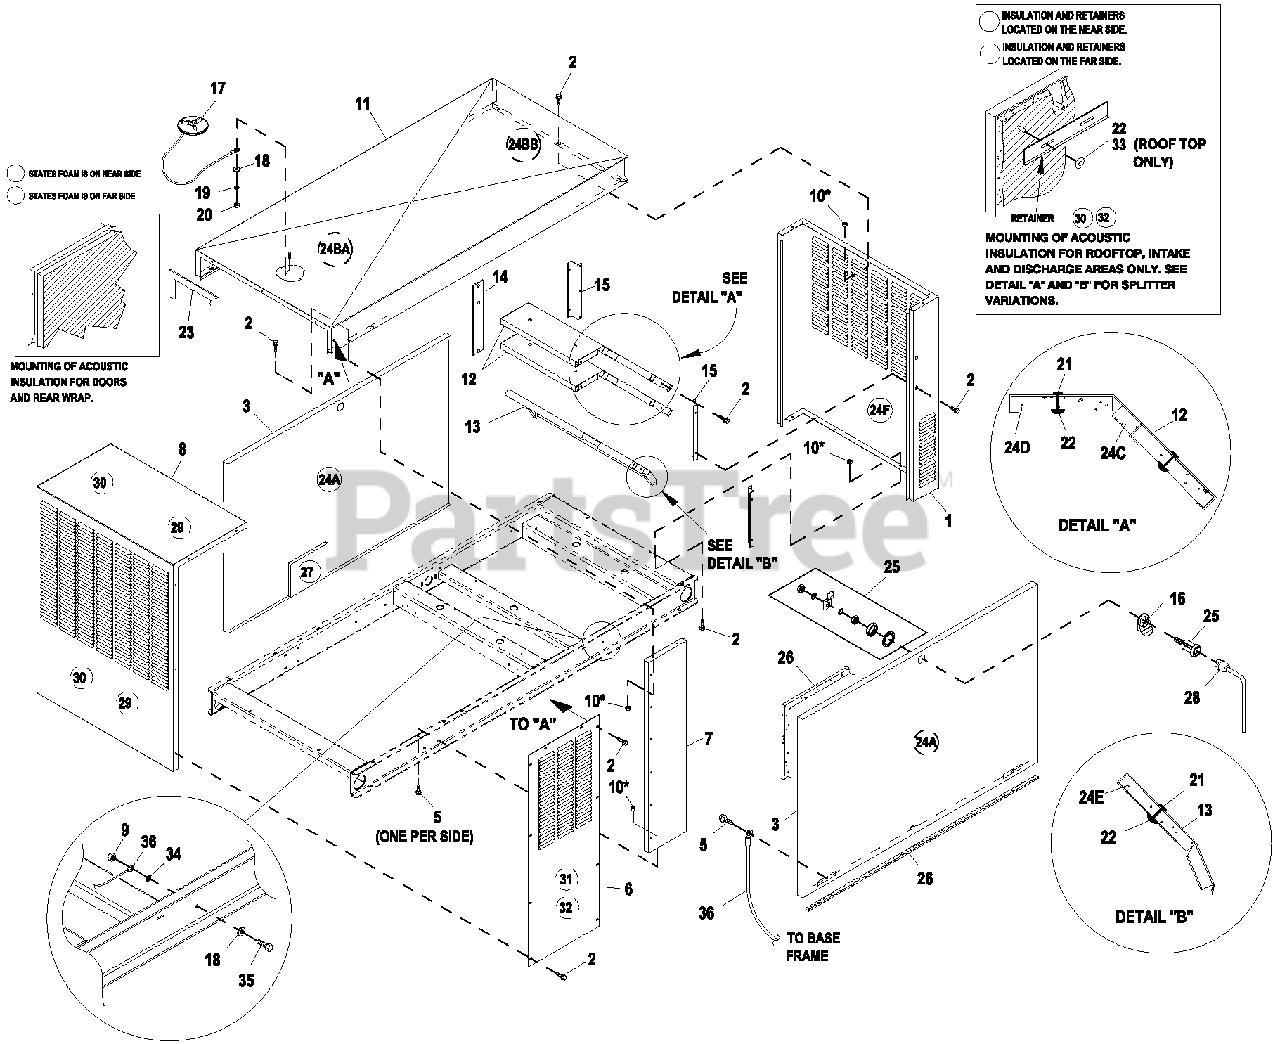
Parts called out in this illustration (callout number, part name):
1	REAR WRAP C2 CPL
2	SCREW THF M6-1 X 16 N WA Z/JS
3	D OOR C2
4	RIVET POP.1875 X .450 SS
5	SCREW TH-FRM M6 W/CAP SHKPRF W
6	DISCHARGE DUCT LH & RH SI D E C2
7	FRONT CORNERS C2
8	DISCHARGE CENTER DUCT C2
9	NUT HEX M6X1.0 G8 YEL CHR
10	NUT HEX LOCK M6-1.0 SS NY INS
11	ROOF C2
12	SLITTER C4
13	SPLITTER LOWER C4
14	SPLITTER STINGER C2
15	SUPPORT SPLITTER LHC2
16	TAB PULL
17	ASSEMBLY COVER ACCESS
18	WASHER FLAT 1/4-M6 ZINC
19	WASHERLOCK M6-1/4
20	NUT HEX 1/4-20 STEEL
21	INSULATION RETAINMENT HANGER
22	WASHER SELF LOCKING DOME #4-40
23	STRIP SEALANT 1/8X 1 (44.52"LG)
24	KIT INSULATION C2
24A	INSULATION D OOR C2
24B	KIT INSULATION C2
24BA	INSULATION ROOF TOP
24BB	INSULATION ROOF TOP
24C	INSULATION SPLITTER
24D	INSULATION SPLITTER
24E	INSULATION LOWER SPLITTER
24F	INSULATION REAR WRAP
25	VISE-ACTION LATCH SLOTTE D CIR
26	GASKET EXTRUDED TRIM (328" LG)
27	FOAM 300 X 300 THERMAL ACO (APPLIES TO 4.2L UNITS ONLY)
28	KEY VISE-ACTION LATCH SLOT CIR
29	INSULATION D UCT
30	RETAINER INSULATION (820)
31	INSULATION D UCT SI D ES
32	RETAINER INSULATION (450)
33	WASHER SELF LOCKING DOME #8-32
34	WASHER SHAKEPROOF INT 1/4
35	SCREW HHC M6-1.0X20 G8.8
36	ASSY WIRE 14 AWG 34.8" GRN/YEL
